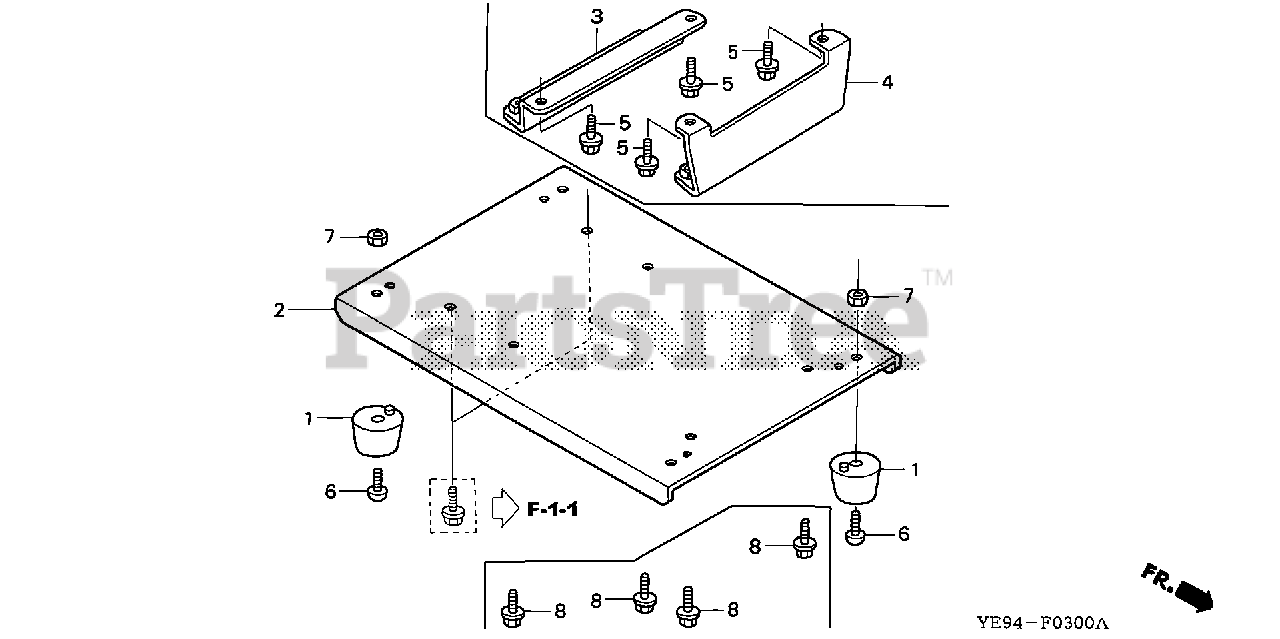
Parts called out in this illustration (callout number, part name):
1	RUBBER (LOWER)
2	BED, FRAME
3	BRACKET A, ENGINE
4	BRACKET B, ENGINE
5	BOLT, FLANGE (5X12)
6	SCREW, PAN (6X10)
7	NUT, HEX. (6MM)
8	BOLT, FLANGE (6X14)
